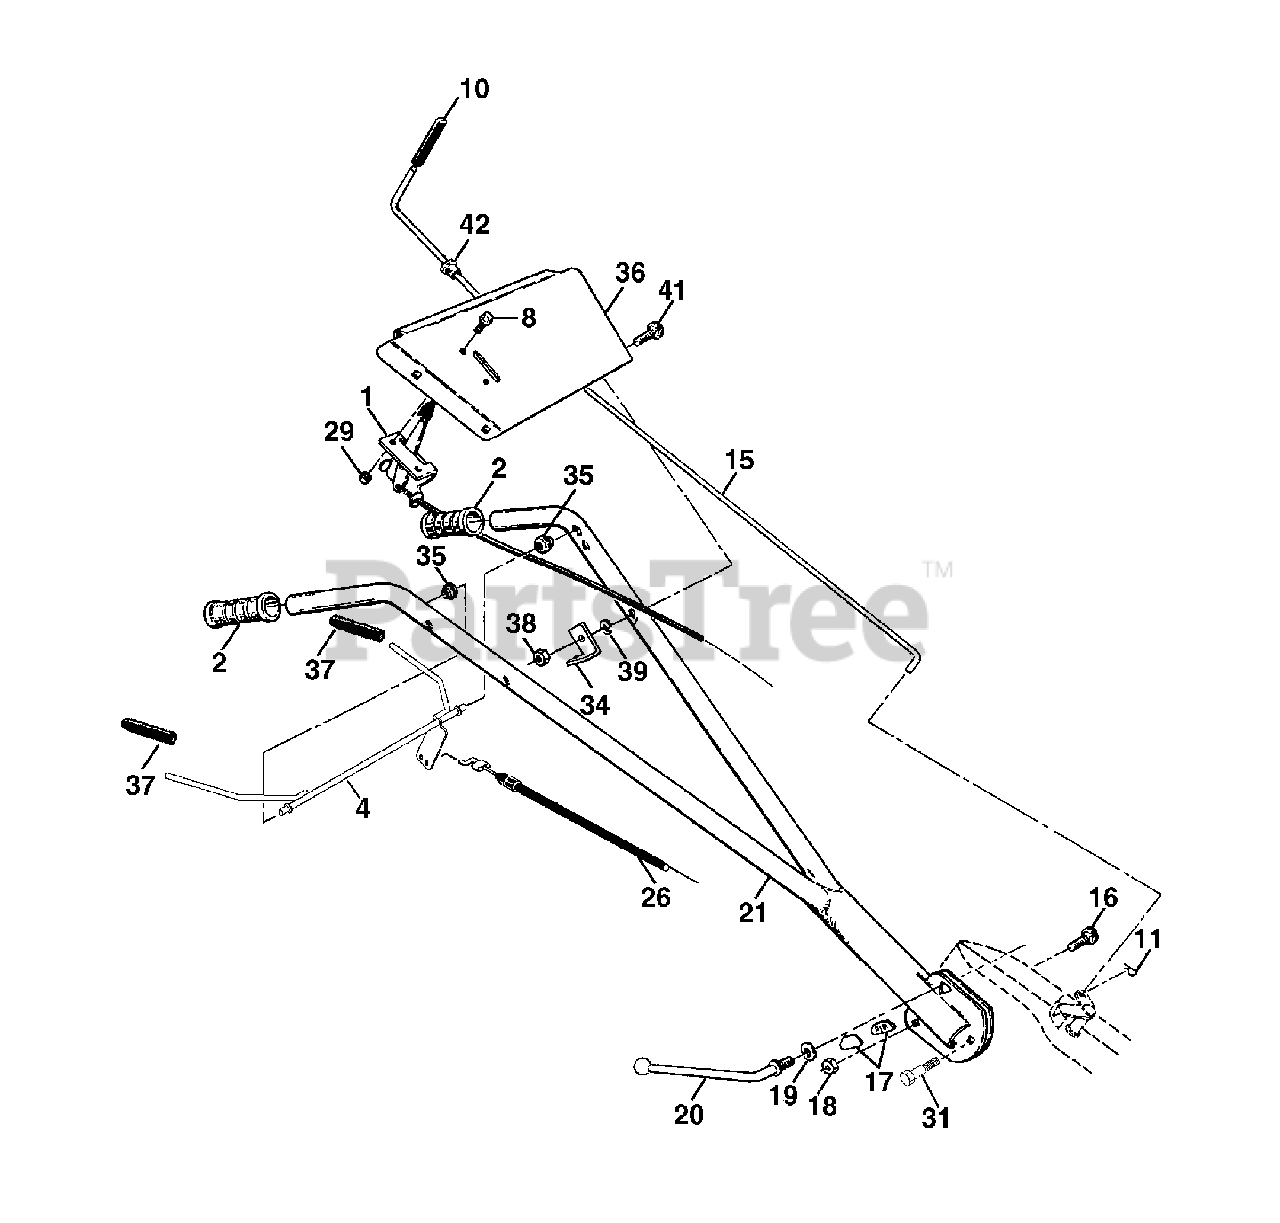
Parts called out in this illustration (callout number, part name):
1	Control, Throttle
2	Grip, Handle
4	Bar, Control
5	Bolt, Carriage 5/16-18 x 1-3/4
8	Screw, Pan Hd. #10-24
10	Grip, Handle
11	Clip, Hairpin
15	Rod, Shift
16	Bolt, Carriage 3/8-16 x 1 Gr. 5
17	Lock, Handle
18	Nut Crownlock 3/8-16 UNC
19	Washer 13/32 x 1 x 11 Ga.
20	Lever, Lock, Handle
26	Cable, Clutch
29	Nut, Keps #10-24 UNC
31	Bolt, Pivot
34	Bracket, Clutch Cable
35	Grommet, Handle
36	Bracket, Handle
37	Grip, Bar Control
38	Locknut 5/16-18
39	Washer, Lock 5/16
42	Bushing, Snap
